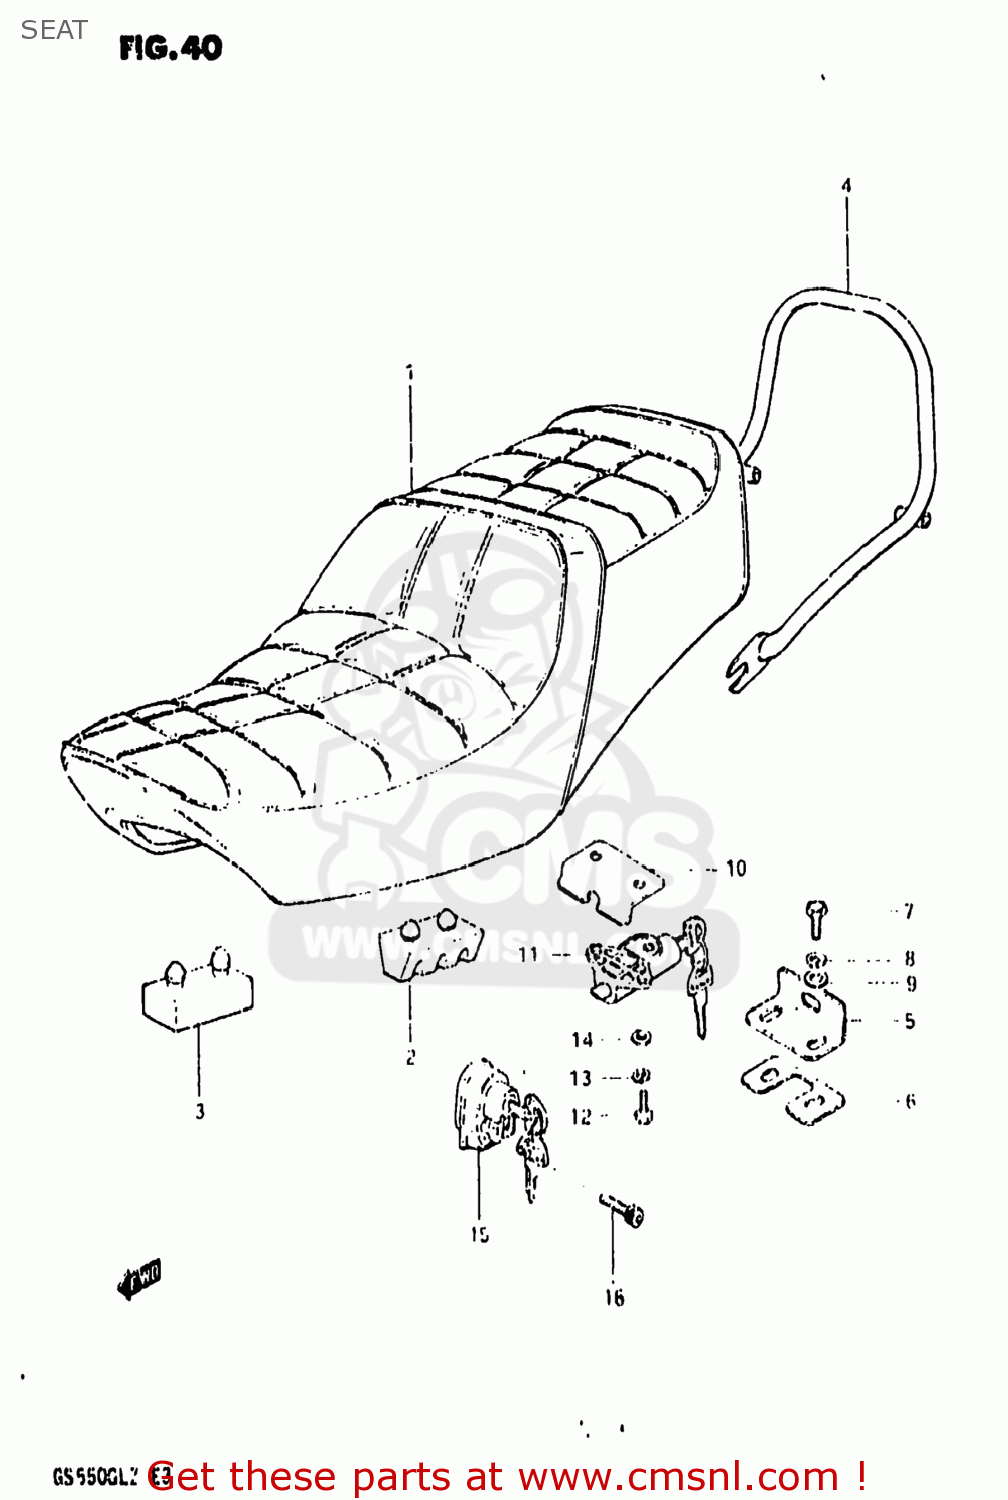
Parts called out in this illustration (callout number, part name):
1	SEAT ASSEMBLY
2	CUSHION,SUPPORT(50X25X32)
3	CUSHION
4	HANDLE,PILLION RIDER
5	STRIKER, SEAT LOCK
6	SHIM,SEAT LOCK STRIKER
7	BOLT, UPPER
8	LOCK WASHER
9	WASHER
10	GUIDE, PLATE
11	LOCK ASSEMBLY,SEAT
12	BOLT
13	LOCK WASHER
14	WASHER
15	LOCK ASSY,HELMET
16	BOLT 5X25
